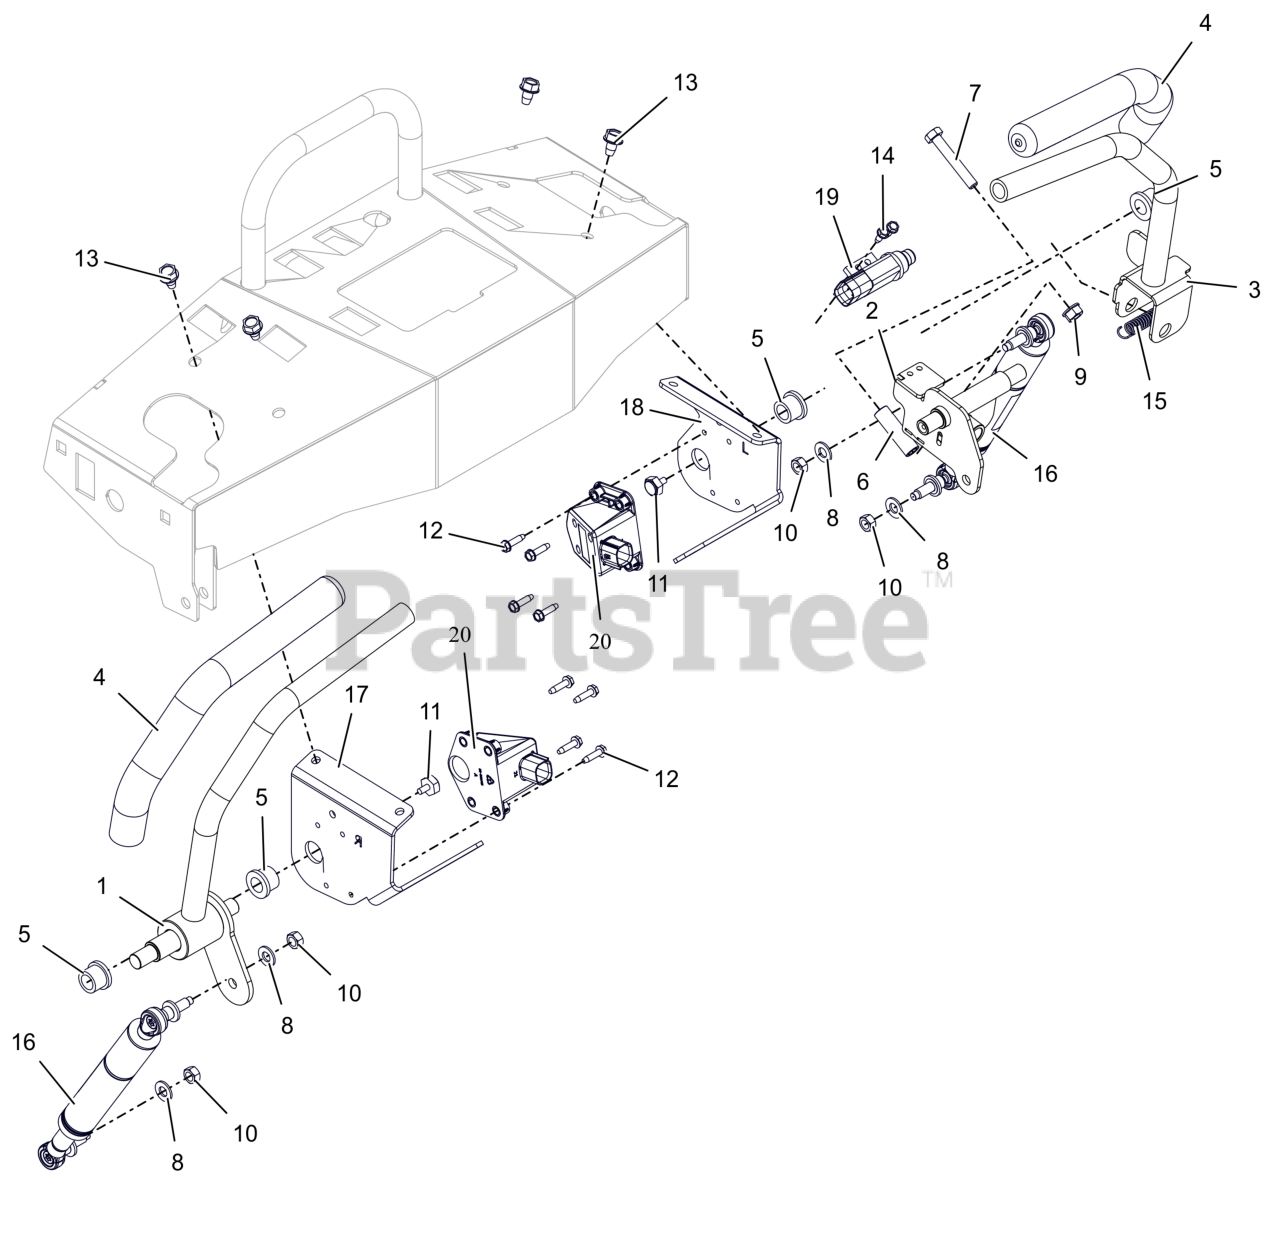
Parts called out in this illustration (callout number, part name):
1	WLDMT, RH DRIVE CONTROL (BLACK)
2	WLDMT, LH DRIVE CONTROL (BLACK)
3	WLDMT, LH HANDLE ASM
4	GRIP, HANDLEBAR
5	BSHG, FLG .516X.750X.625X.937
6	BSHG, SLV
7	BLT, HEX .31-18X2.00 G5 ZCC
8	WSHR, HRDN 0.344X0.688X0.065
9	NUT,LK-CTR-FLG .31-18 GF ZCC
10	NUT, HEX-JAM CTR-LK M8-1.25 ZCC
11	BOLT, MAGNETIC STEERING SENSOR
12	SCR, TAP #10-24X.75 HWH ZCC
13	SCR,TAP .312-18X.50 HWH TR ZCC
14	SCR,TAP #10-24X.50 HWH TR ZCC
15	SPRING, EXT. .043X.438X1.64
16	DAMPER, NEUTRALIZING
17	BRKT, RH DRIVE CONTROL MTG (BLACK)
18	BRKT, LH DRIVE CONTROL MTG (BLACK)
19	SWITCH, SEALED PLUNGER
20	SENSOR, STEERING
